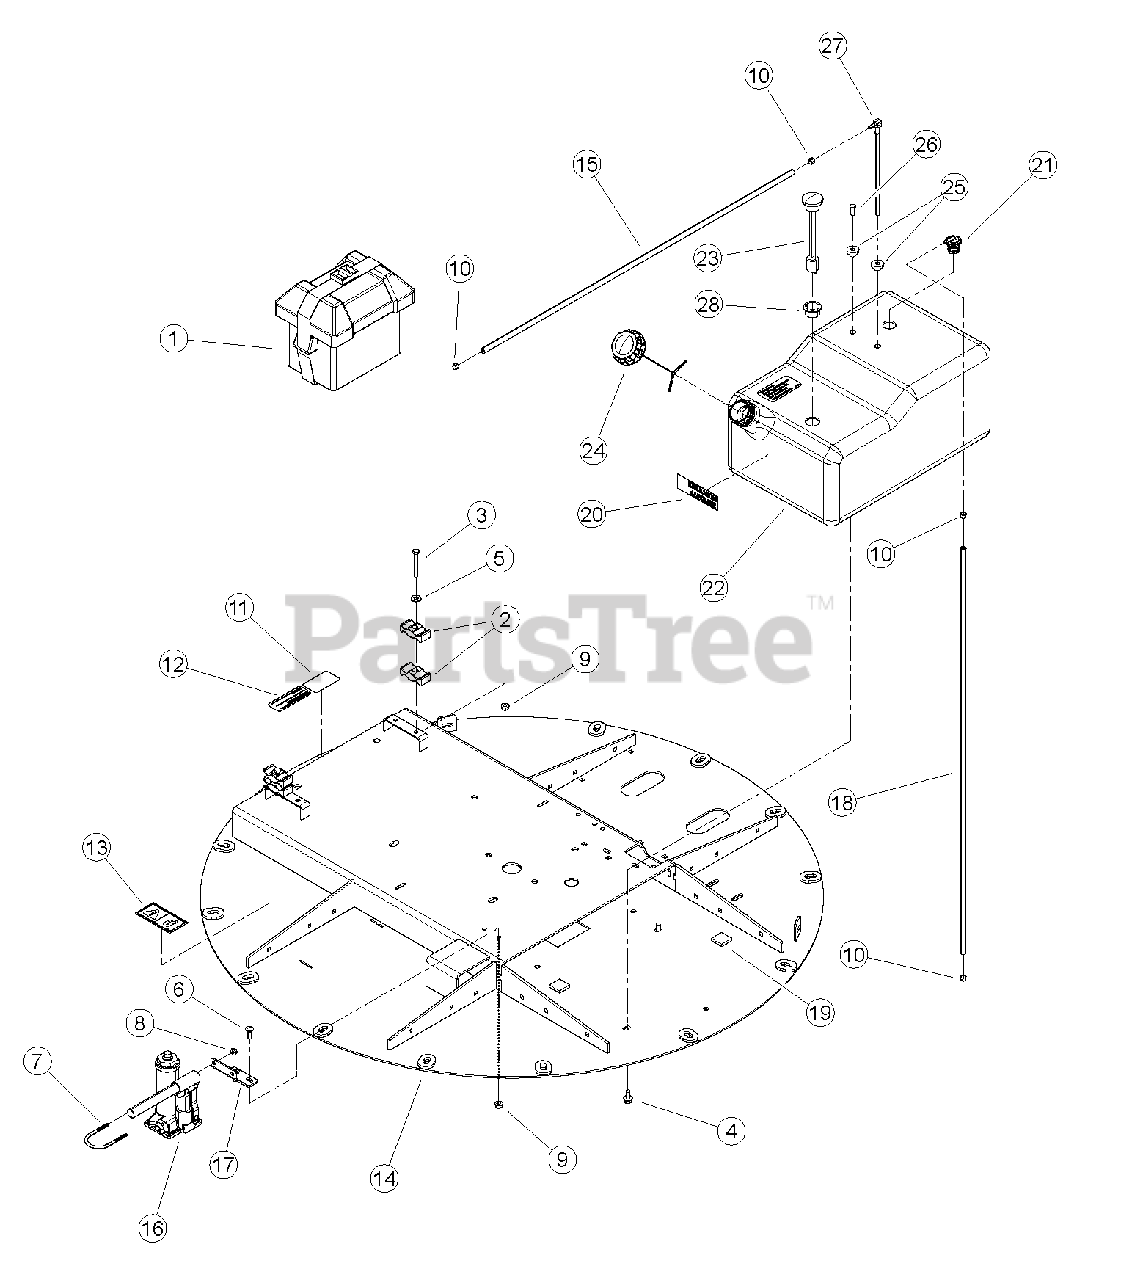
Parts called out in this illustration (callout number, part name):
1	BOX, SMALL BATTERY
2	CLAMP, PLASTIC HOSE
3	BOLT, 5/16 X 2-1/2 G5 HEX CAP ZP
4	BOLT, 3/8 X 3/4 FLANGE NC
5	WASHER, 5/16" FLAT ZP
6	BOLT, 5/16" X 1" GR5 CRG ZP
7	U-BOLT, 1/4 X 1-1/2 PIPE
8	NUT, 1/4-20 NYLOCK-FLANGE
9	NUT, 5/16-18 NYLOCK-FLANGE
10	CLAMP, 15/32 SPRING
11	DECAL, P215/70R15 LOAD RATING
12	DECAL, EPA EVAP
13	DECAL, LOCK
14	WELDMENT, CHIPPER BASE
15	HOSE, 38" FUEL LINE
16	JACK, HYDRAULIC 2 TON
17	PLATE, JACK MOUNT
18	HOSE, 43 INCH FUEL LINE
19	PAD, FOAM FUEL TANK DAMPER
20	DECAL, UNLEADED GASOLINE
21	VALVE, ROLL OVER
22	TANK, ROTOMOLDED FUEL
23	GAUGE, FUEL LEVEL KELCH 100
24	CAP, NON-VENTED EPA/CARB APPROVED
25	GROMMET, TANK FITTING
26	PLUG, TANK VENT
27	FITTING, TANK FUEL PICK-UP TUBE
28	GROMMET, KELCH 100 GAUGE
